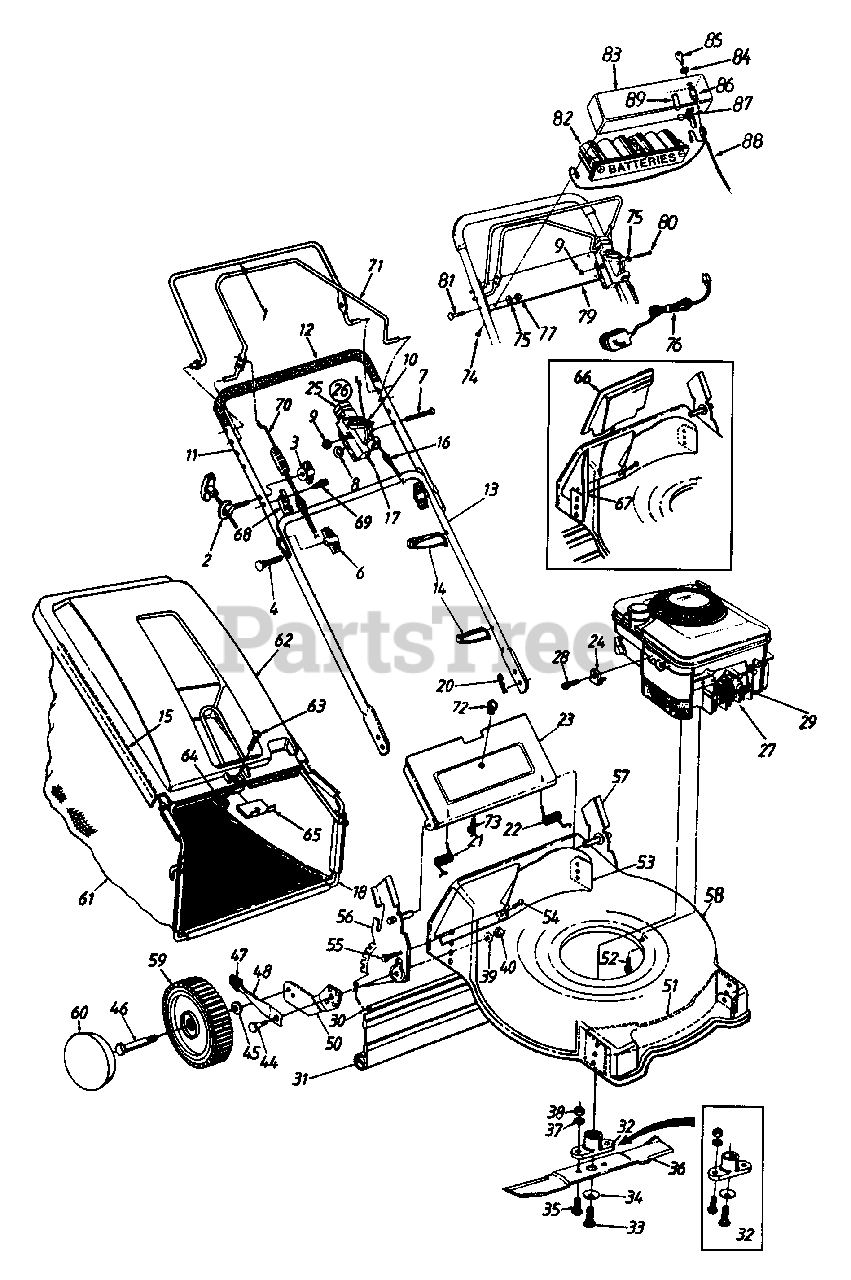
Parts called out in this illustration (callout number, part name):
2	Rope Guide
3	Handle Knob 1/4 - 20 Thd.
4	Curved Hd. Bolt 5/16 - 18 x 2" Lg.
6	Hand Knob
7	Oval C-Sunk Mach. Scr.
8	Spr. Wash. .66" I.D.
9	Hex L-Nut 1/4 - 20 Thd.
10	Throttle Lever
14	Cable Tie
16	Control Cable - 39" (450)
16	Control Cable - 36" (456, 458)
16	Control Cable - 51" (455)
17	Throttle Control Wire - 42" (455)
17	Throttle Control Wire - 55" (450, 456, 458)
21	Door Spring - R.H.
22	Door Spring - L.H.
24	Cable Clamp (B&S)
25	Throttle Body
26	Throttle Box Comp. (Incl Ref. 7, 8, 9, 10, 25)
27	Engine
28	Hex Sems Scr. #10 - 32 x .38" Lg. (Tec )
28	Hex Wash. Hd. Scr. #10 - 32 x .62" Lg. (B&S)
29	Spark Plug Boot (Optional)
30	Wire Rod
31	Rear Flap
32	Blade Adapter Kit
33	Hex Bolt 3/8 - 24 x 1.5" Lg.
34	Bell-Wash. .39" I.D.
35	Hex Bolt 3/8-24 x 1" Lg.
36	21" Blade
36	21" Mulching Blade (Optional)
37	L-Wash. 3/8" I.D.
38	Hex Nut 3/8 - 24 Thd.
39	Bell-Wash. .39" I.D. x 1.38"
40	Hex Nut 3/8-16 Thd.
44	Shld. Bolt .5" Dia. x .357"
45	Bell-Wash. .38" I.D. x .88" O.D.
46	Axle Bolt
47	Spring Lever Knob
48	Spring Lever
50	Pivot Bar
54	Torx Mach. AB-Tap Scr. 1/4 x .62" Lg.
55	Hex L-Wash. Hd. AB-Tap Scr. 1/4 x .62" Lg.
56	Handle Brkt. Ass'y. - R.H.
57	Handle Brkt. Ass'y. - L.H.
60	Hub Cap 3-1/2" Dia. (Gray - Optional)
60	Hub Cap 5-1/2" Dia. (Gray - Optional)
60	Hub Cap 5-1/2" Dia. (Beige - Optional)
61	Grass Bag
62	Hard Top Cover
63	Pan Hd. Mach. Scr. 1/4 - 20 x .5" Lg.
64	Hex Nylon L-Nut 1/4 - 20 Thd.
68	Cable Mtg. Brkt.
69	Hex Wash. AB-Tap Scr. 5/16" x .75" Lg.
70	S.P. Cable 44.75" Lg.
73	Truss Mach. Scr. #10 - 24 x .38" Lg.
74	Pan Hd. Scr. #12 x 3/4" Lg.
75	Bell-Wash. 1/4" I.D.
76	Charger
77	Hex Nut 1/4 - 20 Thd.
78	L-Wash. 1/4" I.D.
81	Curved Hd. Bolt 1/4 - 20 x 1.25" Lg
82	Battery Pack
83	Upper Battery Tray
84	Key Switch
85	Key
86	Fuse Holder
87	Plug
88	Harness
89	Fuse 7-1/2 Amp.
